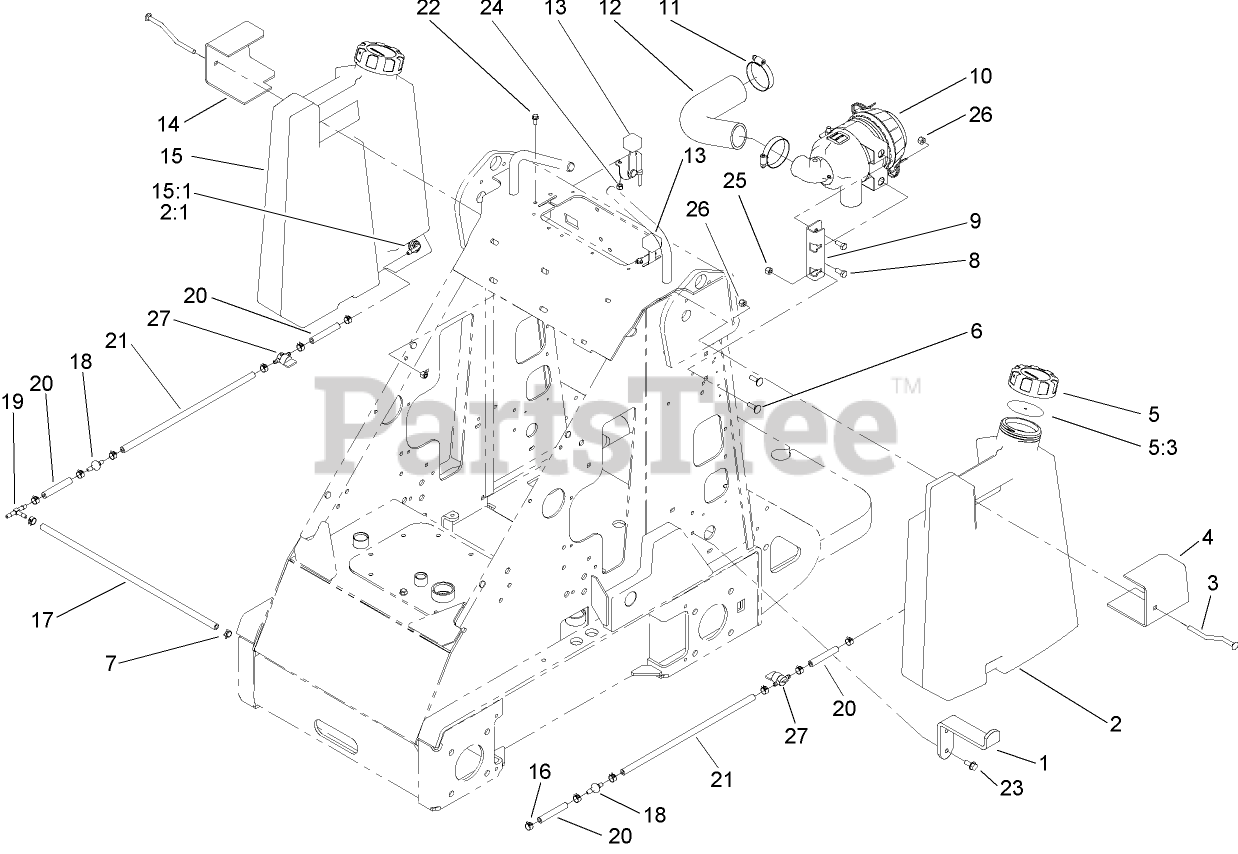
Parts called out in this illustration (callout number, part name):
1	MOUNT-BOTTOM, TANK
2	LH Fuel Tank ASM
2:1	FITTING-FUEL, BULKHEAD
3	BOLT-MOUNT
4	PLATE-MOUNT, LEFT
5	CAP-FUEL, GAS
5:3	GASKET-VENTED
6	BOLT-CARR
7	CLAMP-HOSE
8	SCREW-HH
9	MOUNT-CLEANER, AIR
10	AIR CLEANER ASM
11	CLAMP-HOSE
12	HOSE-AIR
13	CONTROL-CHOKE / THROTTLE
14	PLATE-MOUNT
15	RH Fuel Tank ASM
15:1	FITTING-FUEL, BULKHEAD
16	CLAMP-HOSE
17	HOSE-FUEL
18	VALVE-CHECK, FUEL
19	FITTING-TEE, BARBED
20	HOSE-FUEL
21	HOSE-FUEL
22	SCREW-HHF
23	SCREW-HWHTF
24	NUT-LOCK, NI
25	NUT-HF
26	NUT-LOCK, NI
27	VALVE-FUEL
